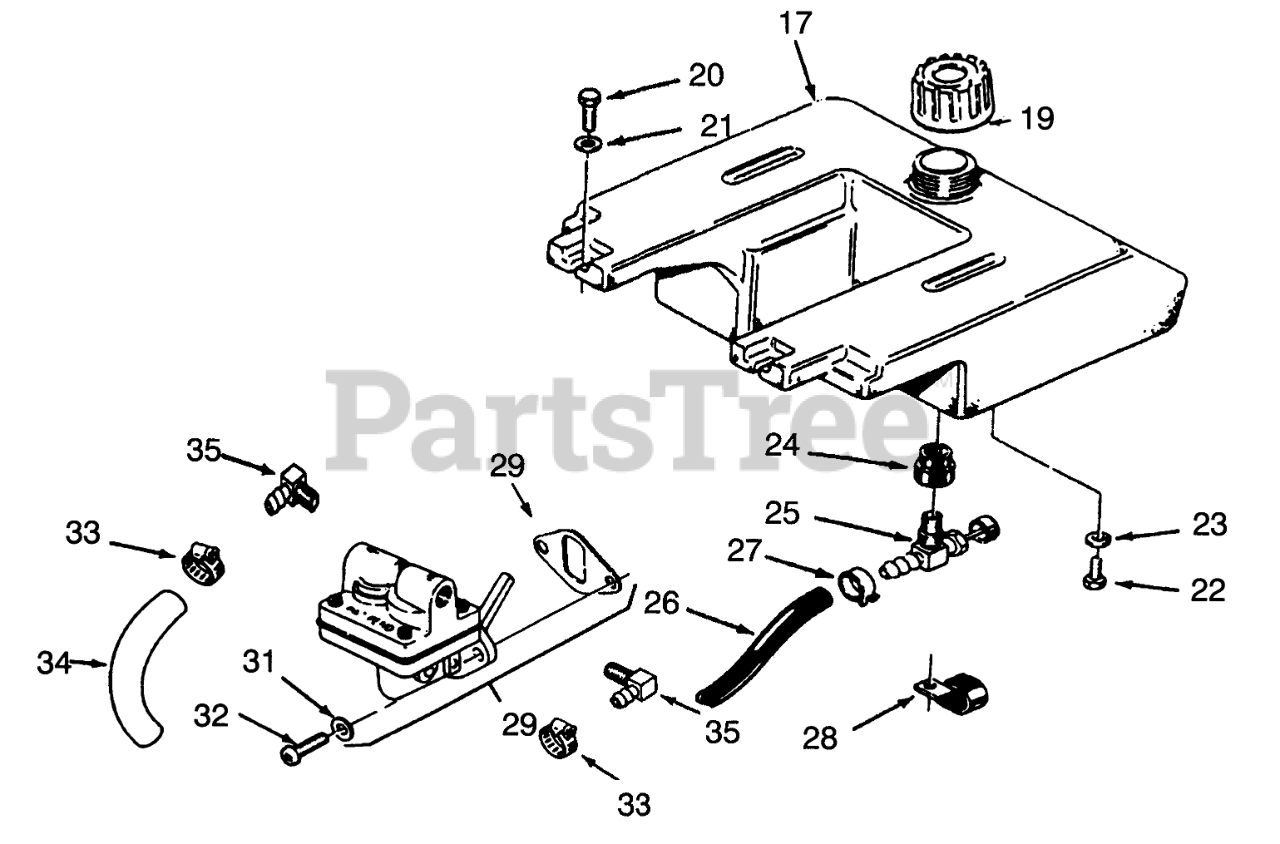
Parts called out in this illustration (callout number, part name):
17	TANK-FUEL
19	GAS CAP ASM
20	Bolt
21	WASHER-FLAT
22	SCREW-HH
23	WASHER-LOCK
24	BUSHING
25	VALVE-FUEL
26	Fuel Line 62
27	Clamp
28	Clamp
29	Pump Assy-Fuel (Incl. Ref. #30 & 31)
30	Gasket
31	Washer
32	Screw-Pozidrive
33	Clamp
34	Line-Fuel
35	Connector 90
